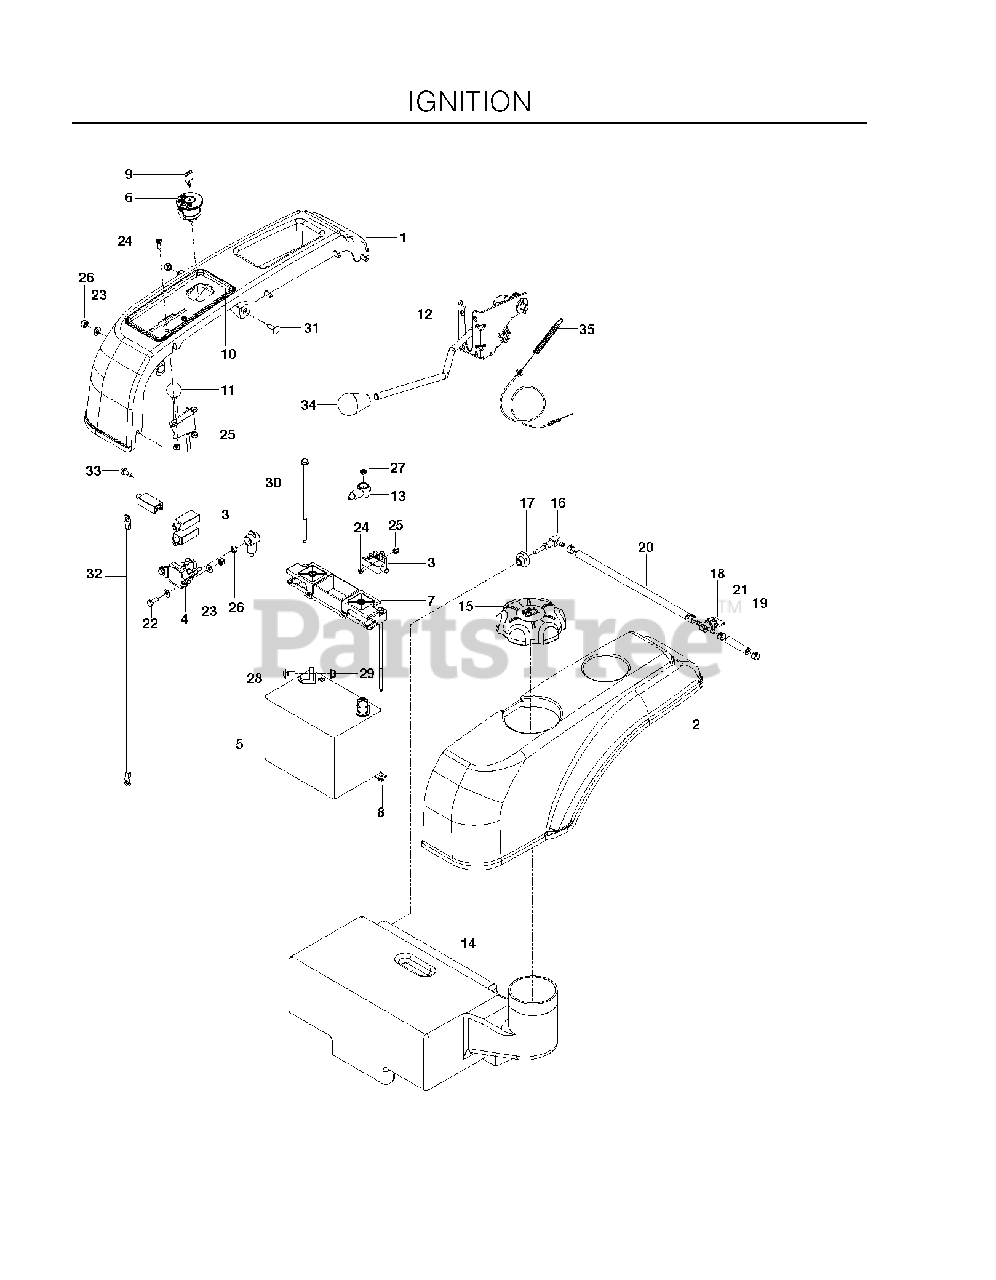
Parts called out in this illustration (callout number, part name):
1	FENDER RH
2	FENDER LH
3	SWITCH, INTERLOCK
4	SOLENOID
5	BATTERY, 12 V 330 AMP TBR
6	IGNITION SWITCH
7	BATTERY HOLD DOWN
8	PUSH NUT-NYLON
9	KEY
10	MOUNT, CONTROLS, BLK
11	CABLE, THROTTLE
13	TERMINAL COVER-SM
14	FUEL TANK
15	FUEL CAP, GENERIC
16	ELBOW W/FILTER
17	TANK FITTING
18	FUEL VALVE
19	HOSE CLAMP
20	HOSE 1/4 X 8
21	HOSE 1/4 X 2"
22	HCS 1/4C X 3/4 HCS
23	WASHER 1/4 SAE
24	SCREW #10-24 X 5/8
25	NUT 10-24 NYLOC
26	NUT 1/4-20 NYLOC
27	JAM NUT 1/4C
28	BOLT 5/16C X 3/4" CARRIAGE
29	5/16-18 NYLOC FLANGE NUT
30	BOLT - 1/4-20 X 7.5
31	RHSNB 1/4C X 3/4
32	BATTERY CABLE, NEGATIVE
33	SCREW 1/4 X 5/8
34	KNOB - SHIFT
35	CABLE.CLUTCH.38".SERVICE
